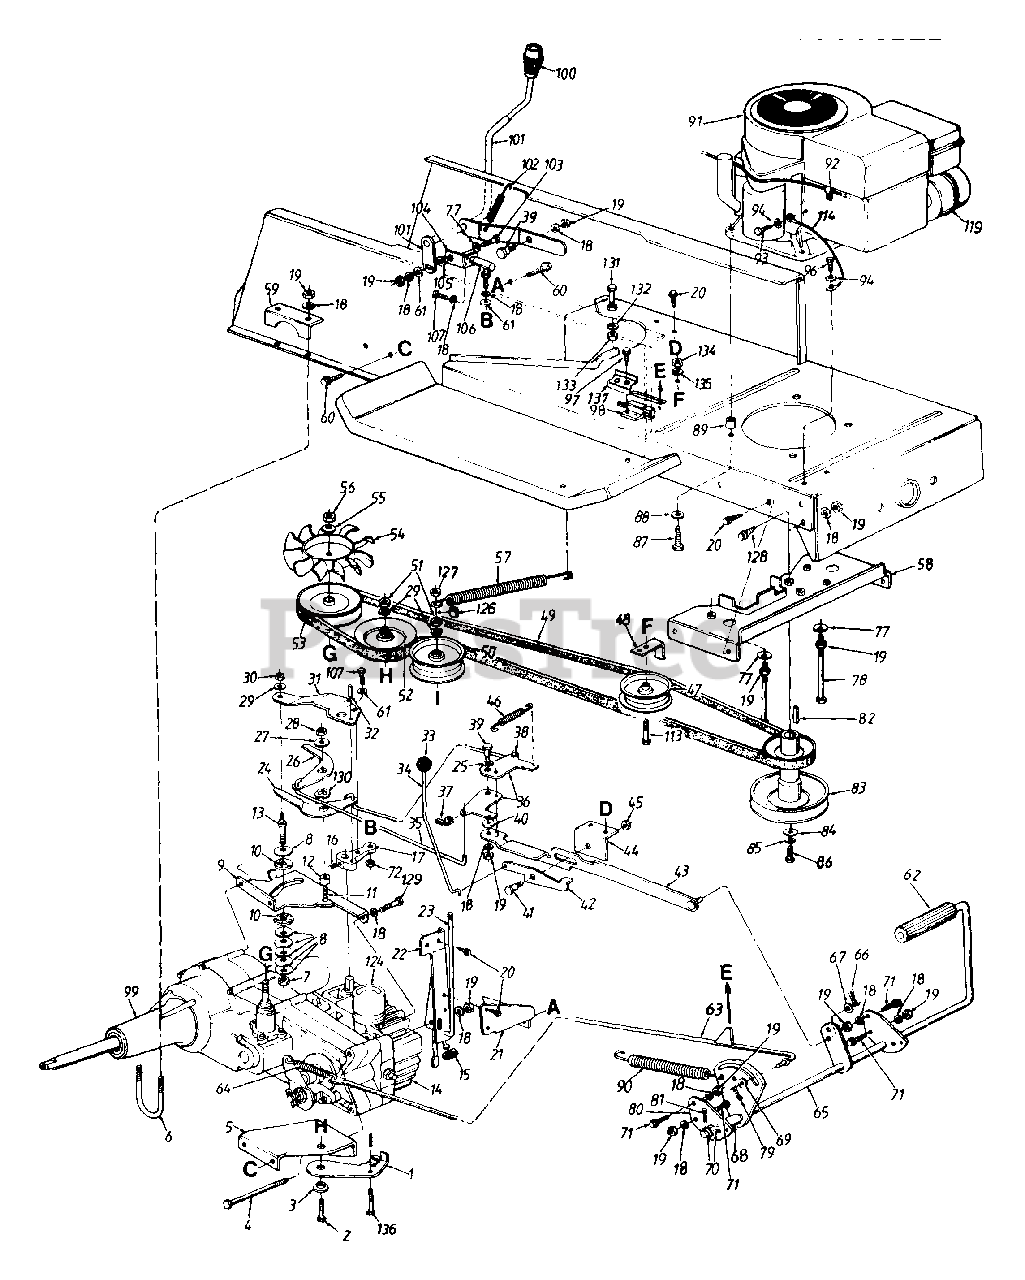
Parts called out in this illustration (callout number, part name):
1	Idler Bracket
2	Hex Bolt 3/8-16 x 2.0" Lg.
3	Shld. Spacer .625" I.D.
4	Hex Bolt 5/16-18 x 4.5" Lg. (Gr. 5)
5	Idler Plate
6	U-Bolt 5/16-18 x 1.75" Lg.
7	Hex L-Nut 3/8-24 Thd.
8	Bell-Wash..40" I.D. x 1.13"
9	Mounting Bracket
10	Friction Washer
11	Rib Neck Bolt 5/16-24 x .84" Lg.
12	Spacer
14	Hydrostatic Pump
15	Rubber Washer .33" I.D.
16	Set Screw
17	Pintle Shift Lever
18	L-Wash. 5/16" I.D.
19	Hex Nut 5/16-18 Thd.
20	Hex TT-Tap Scr. 1/4-20 x .5"
21	Reinforcement Plate
22	Transmission Torque Brkt.
23	Release Valve Rod
24	Reverse Arm
25	Spring Washer .625" I.D.
26	Forward Arm
27	Fl-Wash..344" I.D. x 1.0"
28	Hex Cent. L-Nut 5/16-24 Thd.
29	L-Wash. 3/8" I.D.
30	Hex Nut 3/8-24 Thd.
31	Pintle Arm Ext. Plate
32	Roll Pin 1/4" Dia. x .75" Lg.
33	Ball Knob
34	Lock-Up Rod
35	Connection Rod
36	Balancer Bracket
37	Rod End Clevis Clips - R.W.
38	Rod End Clevis Clips - L.H.
39	Shld. Bolt .437" Dia. x .268"
40	Fl-Wash..344" I.D. x 1.12"
41	Shld. Bolt .437" Dia. x .35"
42	Lock-Up Bracket
43	Neutral Return Brkt. Ass'y.
44	Bracket
45	Hex Cent. L-Nut 5/16-18 Thd.
46	Ext. Spring 2.5" Lg.
47	Idler Pulley 3.06" O.D.
50	Flat Idler
51	Hex Nut 3/8-16 Thd.
52	Idler Pulley 4.0" O.D.
53	Transmission Pulley
54	Hydro Fan
55	Bell-Wash..569" I.D. x 1.125"
56	Hex Jam Nut 9/16-18 Thd.
57	Extension Spring
58	Belt Guard Brkt. Ass'y.
59	Bracket
60	Hex Wash. Hd. B-Tap Scr. 5/16-18 x .5" Lg.
61	Flat Tooth Washer 5/16" I.D.
62	Foot Pad
63	Brake Rod Ass'y.
64	Ext. Spring 3.67" Lg.
65	Clutch Brake Pedal Ass'y.
66	Intern. Cotter Pin 5/16" Dia.
67	Fl-Wash..385" I.D. x .62"
68	Spacer.63"1 D.
69	Fl-Wash..385" I.D. x .62"
70	Fl-Wash..635" I.D. x 1.0"
71	Hex Wash. TT-Tap Scr. 5/16-18 x 7/8" Lg.
72	Hex Nut 5/16-24 Thd.
77	Bell-Wash..345" I.D. x .88"
78	Hex Bolt 5/16-18 x 4.0" Lg.
79	Cotter 3/32" Dia. x .75" Lg.
82	Sq.-Key 1t4" x 2.0"
83	Engine Pulley
84	Fl-Wash. 7/16" I.D. x 1.25"
85	L-Wash. 7/16" I.D. (H.D.)
86	Hex Bolt 7/16-20 x 1.5" Lg.
87	Hex TT-Tap Scr. 3/8-16 x 1.5"
88	Fl-Wash..406" I.D. x 1.25"
89	Spacer.38" I.D. x 1.25" O.D.
90	Extension Spring 6.11" Lg.
91	Engine
92	Speed Clip
93	Truss Mach. Scr. 5/16-18 x .75"'
94	External L-Wash. 5/16" I.D.
96	Hex AB-Tap Scr. 5/16 x .75"
97	Truss B-Tap Scr. #10 x .5"
98	Safety Switch (Clutch)
99	Transaxle
100	Shift Knob
101	Speed Selector Lever Ass'y.
102	Ext. Spring 2.75" Lg.
103	Hex Bolt 5/16-18 x 1.25" Lg.
104	Connection Brkt.
105	Shoulder Nut
106	Ball Joint 5/16-24 Thd.
107	Hex Bolt 5/16-24 x .75" Lg.
113	Hex Bolt 3/8-24 x 1.75" Lg.
114	Ground Wire 7.25" Lg.
119	Muffler
124	Reservoir
126	Spacer .375" I.D. x .503"
127	Hex Jam Nut 3/8-16 Thd.
128	Hex TT-Tap Scr. 5/16-18 x .62"
129	Hex Bolt 5/16-18 x 43/4" Lg.
130	Spring Washer .625" I.D.
131	Hex Bolt 1/4-20 x 1.25" Lg.
132	L-Wash. 1/4" I.D.
133	Hex Nut 1 4-20 Thd.
134	Hex L-Nut 3/8-24 Thd.
135	Fl-Wash..385" I.D. x .87"
136	Hex Bolt 3/8-16 x 2.5" Lg.
137	Switch Plate
